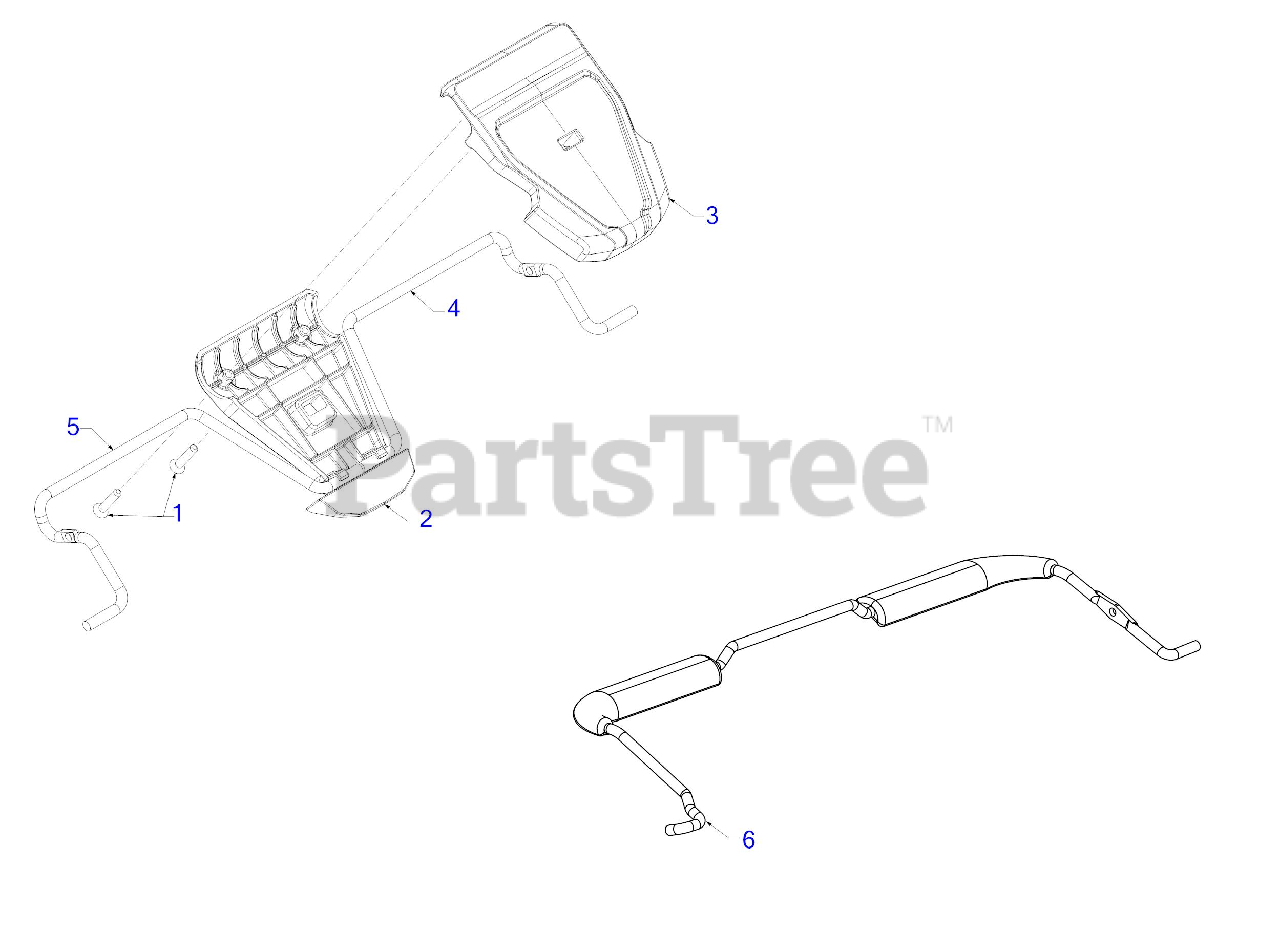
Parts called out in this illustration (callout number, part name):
1	SCREW #10-16 x 1.00
2	LOWER CONTROL HOUSING
3	UPPER CONTROL HOUSING
4	DRIVE BAIL LH
5	DRIVE BAIL RH
6	OPER BAIL ASM STRAIGHT W/OVERMOLD
